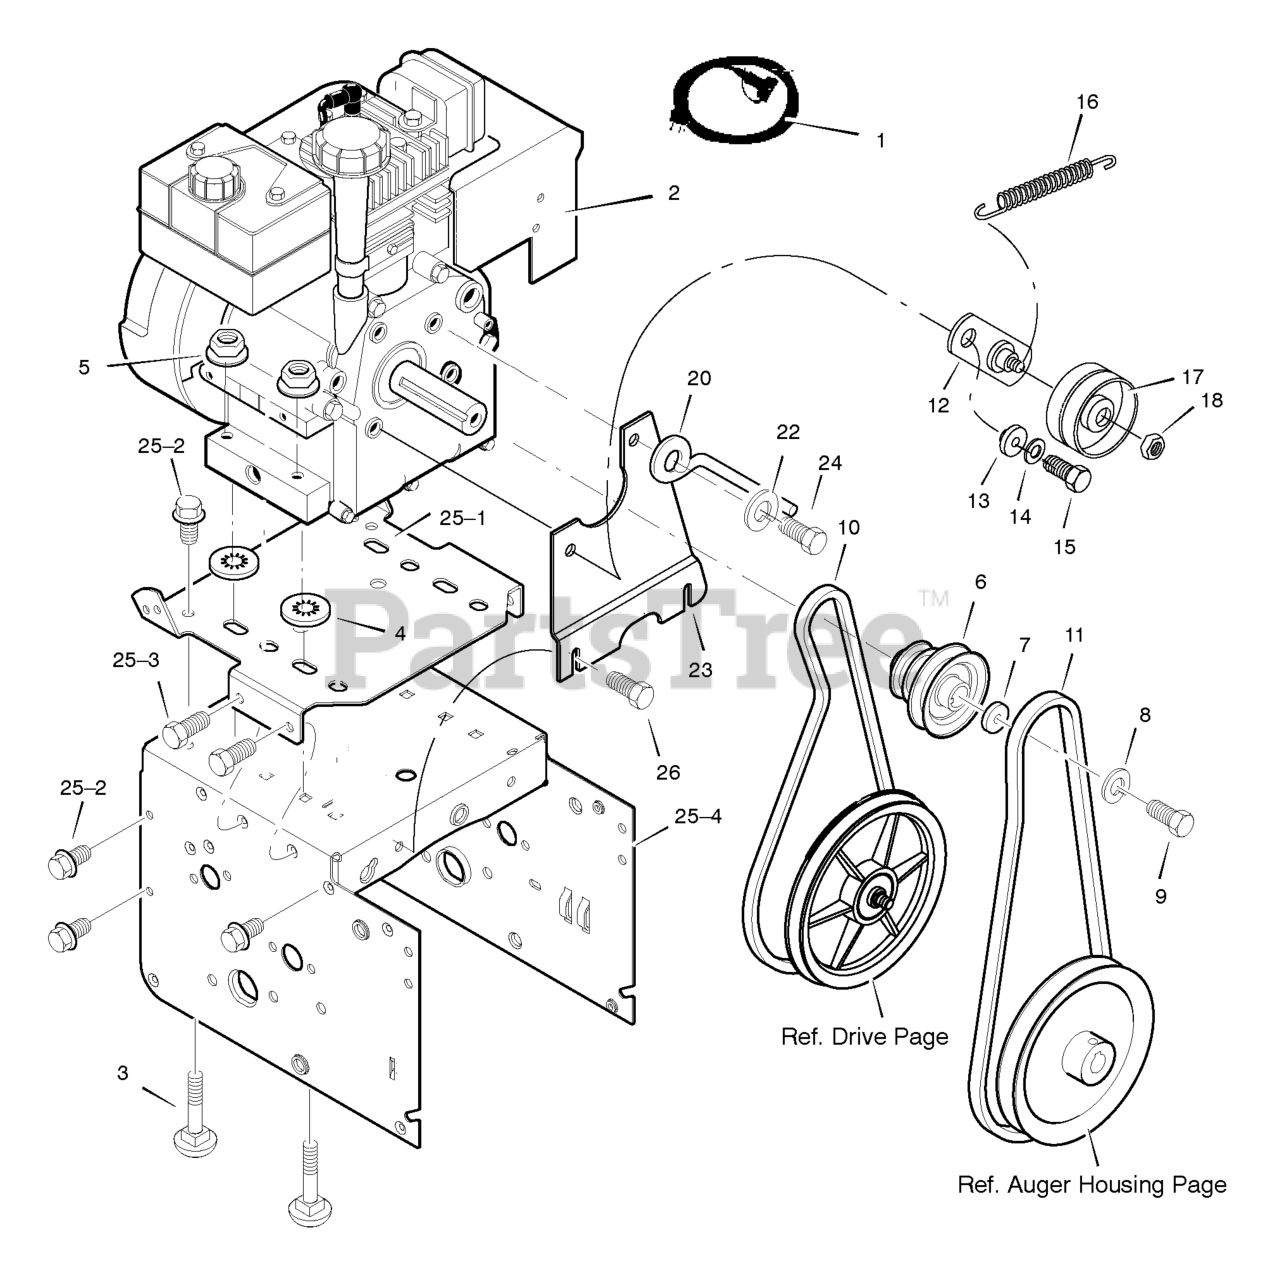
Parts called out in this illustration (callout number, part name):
1	CORD, Electric, 10FT. 110V
2	Engine *
3	BOLT, CARRIAGE 5/16-18
4	RETAINER, PUSH
5	NUT, HEX 5/16-18
6	PULLEY, ENGINE
7	WASHER
8	WASHER .38ID
9	SCREW, 3/8-24 x 1.00
10	BELT, DRIVE V 3L
11	BELT, AUGER V 4L
12	BRACKET ASSEMBLY, IDLER
13	BUSHING, IDLER BRACKET
14	WASHER, SPLIT
15	SCREW 5/16-24 X 1.00
16	SPRING, IDLER TRACTION DRIVE
17	PULLEY, IDLER
18	NUT, JAM 3/8-16
20	GUIDE, BELT
22	WASHER, SPTLK .31X.58X.08
23	PLATE, ANTI VIBRATION
24	SCREW, 5/16-24 x 1.00
25	FRAME ASSEMBLY
25-1	PLATE, ENGINE MOUNT
25-2	SCREW, TAP 1/4-20 X .63
25-3	SCREW, TAP 5/16-18 X .50
25-4	FRAME, MOTOR BOX
